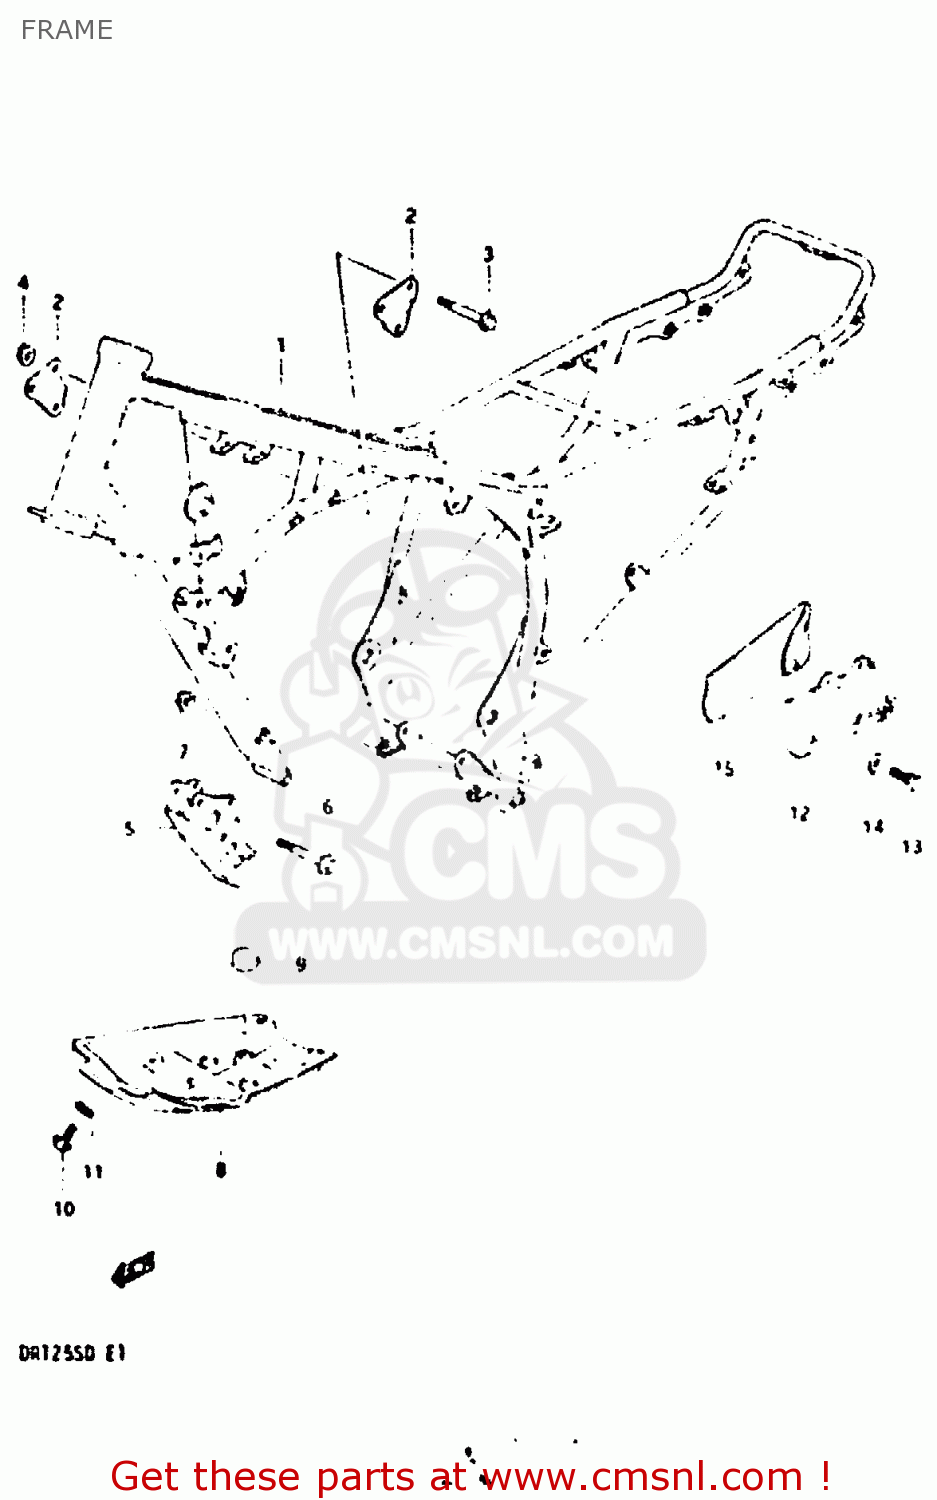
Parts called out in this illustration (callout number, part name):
1	FRAME
2	PLATE,ENGINE MOUNTING
3	BOLT
4	NUT
5	PLATE,ENGINE MOUNTING
6	BOLT
7	NUT
8	PROTECTOR,ENGINE
9	CUSHION
10	BOLT
11	WASHER
12	HOLDER,TOOL
13	BOLT, UPPER
14	WASHER (6.5X18X1.6)
15	TOOL SET
